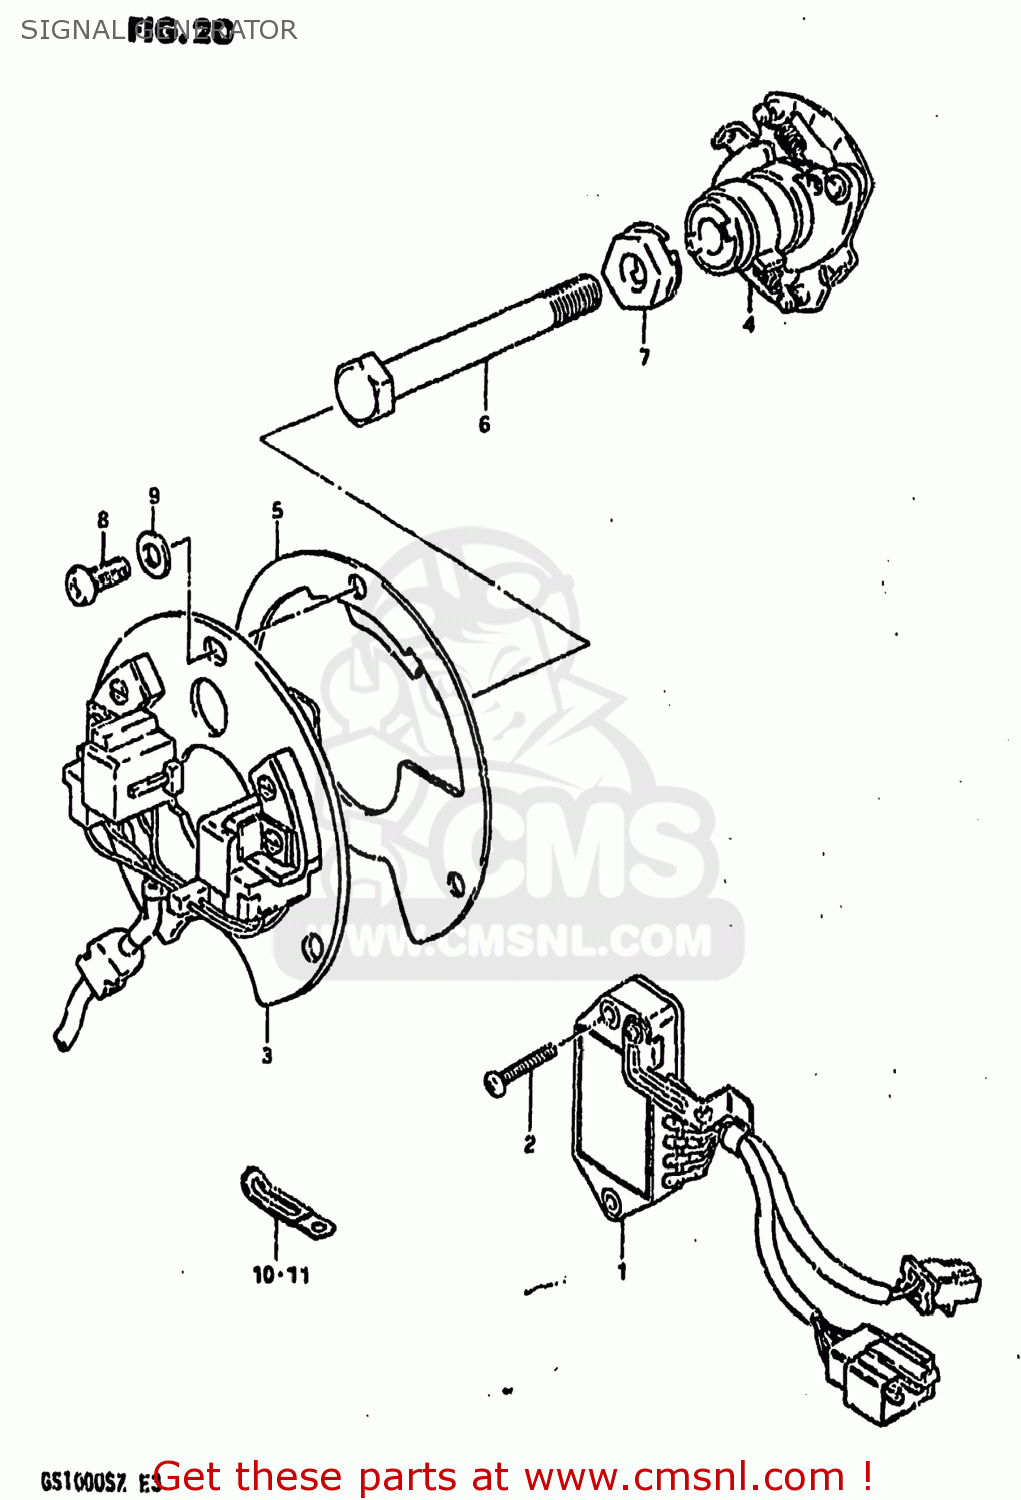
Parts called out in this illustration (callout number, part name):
1	IGNITER UNIT
2	SCREW
3	SIGNAL GENERATOR ASSEMBLY
4	GOVERNOR ASSEMBLY
5	PLATE,TIMING
6	BOLT
7	WASHER
8	SCREW(5X12)
9	WASHER
10	CLAMP L:35
11	CLAMP
